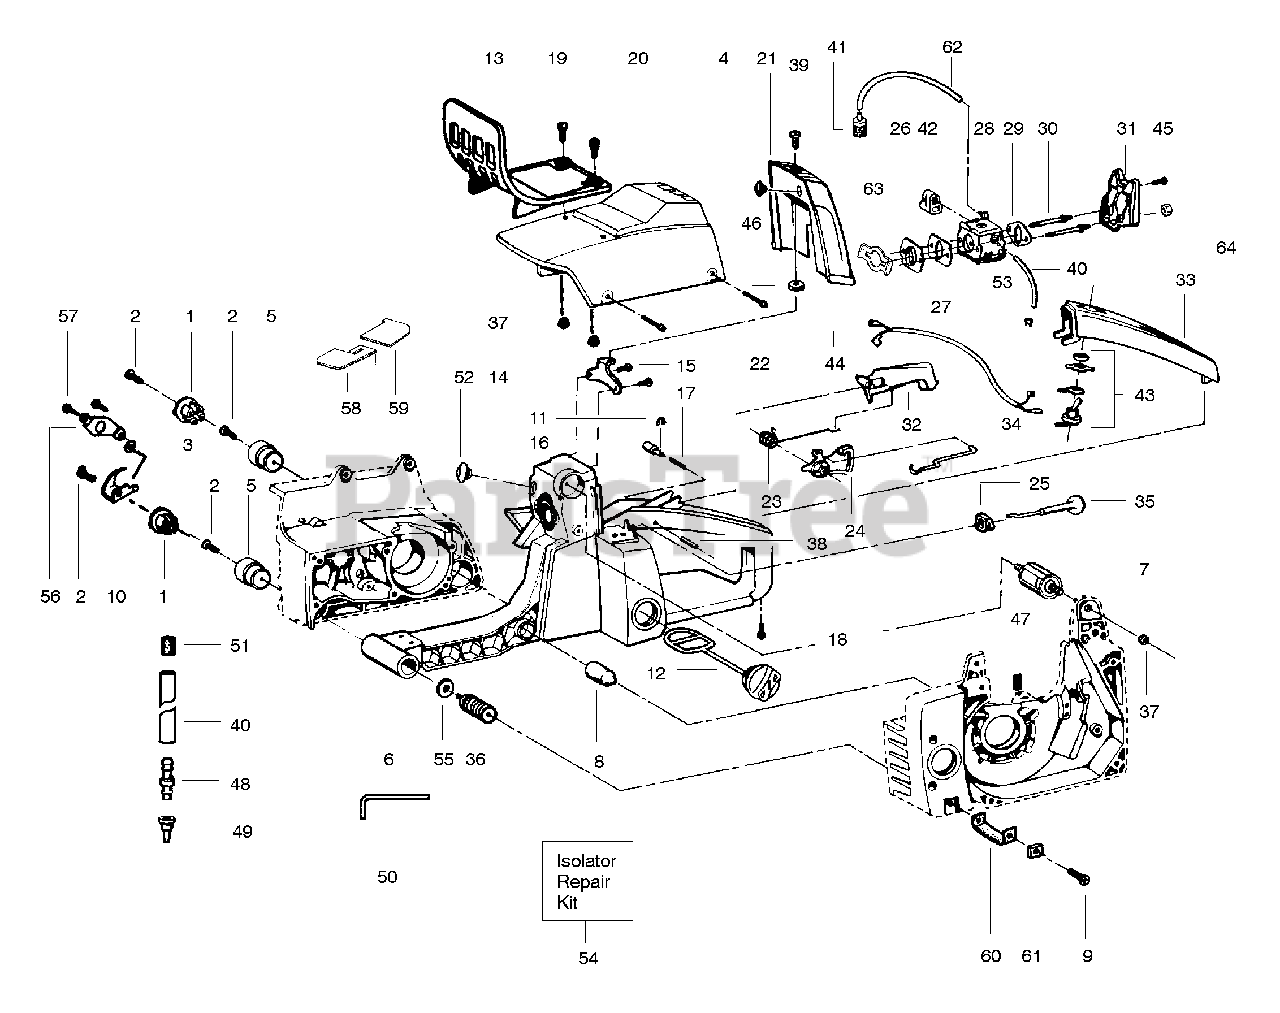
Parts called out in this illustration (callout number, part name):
1	Retainer-Chain Catcher
3	Washer-Flat
4	Carb. Cover Bumper
5	Lower Isolator
6	Rear Handle & Fuel Tank
8	Bumper Isolator
9	Screw
10	Chain Catcher
11	"C" Clip
12	Fuel Cap Ass'y.
13	Handguard
16	Throttle Lock
17	Throttle Spring
20	Cylinder Shield Kit
21	Carb. Cover
22	Screw
23	Trigger Latch Spring
24	Throttle Trigger
27	Engine Gasket Set
28	Carburetor (HDA-49)
29	Air Filter Plate
30	Carb. Mounting Stud
31	Air Filter Ass'y.
32	Throttle Lockout
33	Rear Handle Cover
34	Throttle Wire
35	Choke Knob
36	Isolator Kit
38	Dowel Pin
40	Line Kit (Bulk 530008133)
41	Fuel Pickup Ass'y.
42	Grommet-Carb.
43	Switch Kit
44	Lead Wire Ass'y.
45	Screw
46	Retainer-Screw
47	Impulse Fitting
48	Vent Fitting
49	Check Valve
51	Vent Plug
52	Air Box Plug
54	Isolator Repair Kit
56	Bracket Retainer
58	Carb. Seal-Left
59	Carb. Seal-Right
60	AV Strap
61	Strap Retainer Plate
62	Fuel Line Kit (Bulk 530009078)
63	Bracket-Carb Stud
64	Nut-Air Filter
